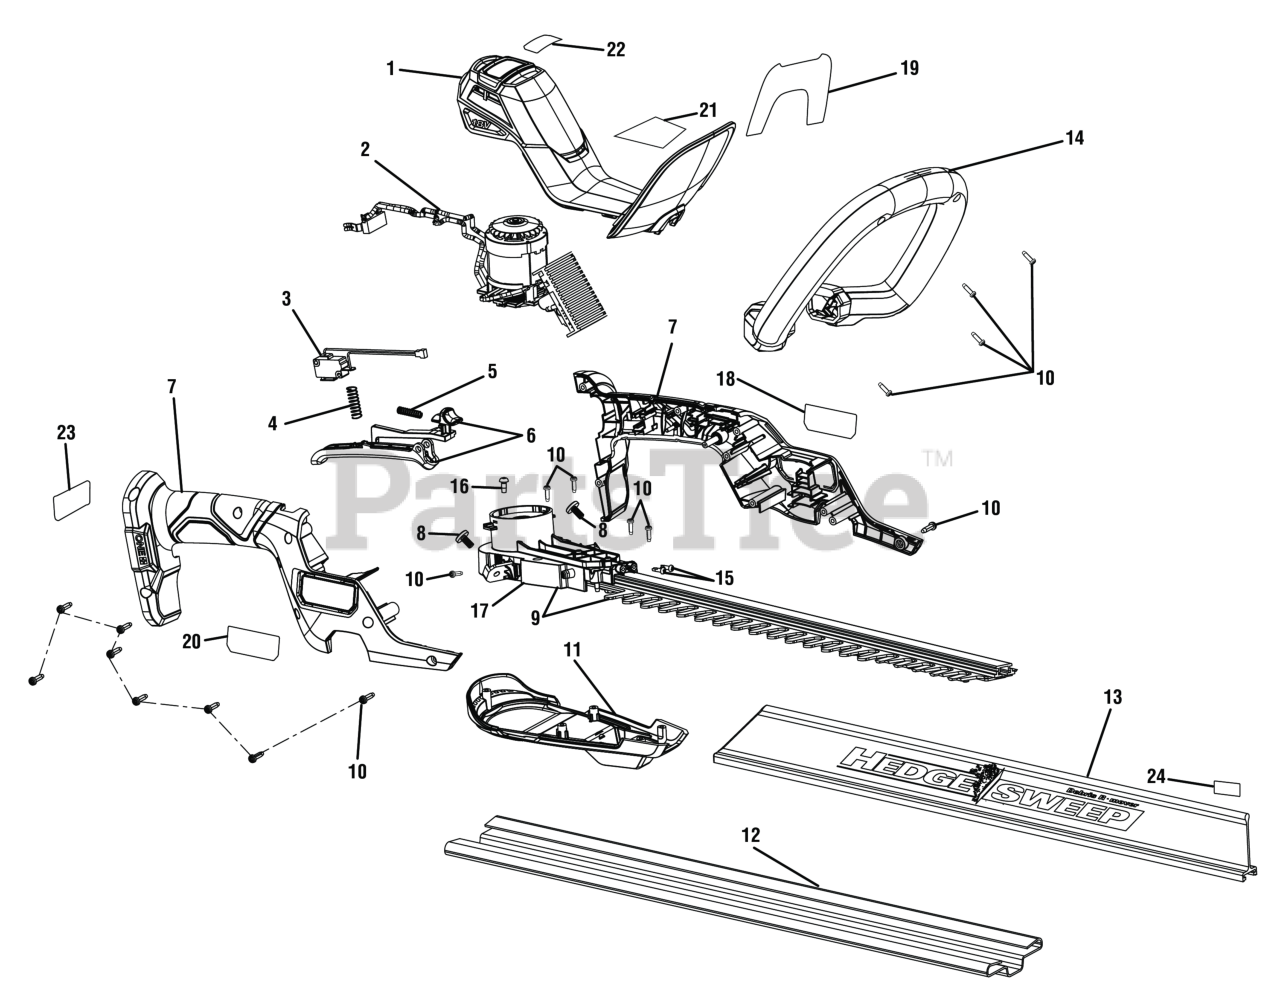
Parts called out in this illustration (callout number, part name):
1	Top Cover Assembly
2	Motor, Controller, and Battery Holder Assembly
3	Switch Assembly
4	Compression Spring
5	Spring, Lockout Button, Dia. 4.6, Soring
6	Trigger Assembly
7	Housing Assembly
8	Screw (M5 x 13 mm, Pan Hd.)
9	Gearbox and Blade Assembly
10	Screw (M4 x 13.5 mm, T15 Torx Pan Hd.)
11	Gearbox Cover
12	Blade Shield
13	Hedge Sweep Assembly
14	Front Handle Assembly
15	Screw (M3 x 10 mm)
16	Screw (M4 x 9 mm, T15 Torx Pan Hd.)
17	Gearbox Housing
18	Logo Label
19	Icon Warning Label (ENG/FR)
20	Data Label
21	Warning Label (SP)
22	Brushless Label
23	Battery Foot Label
24	Warning Label
